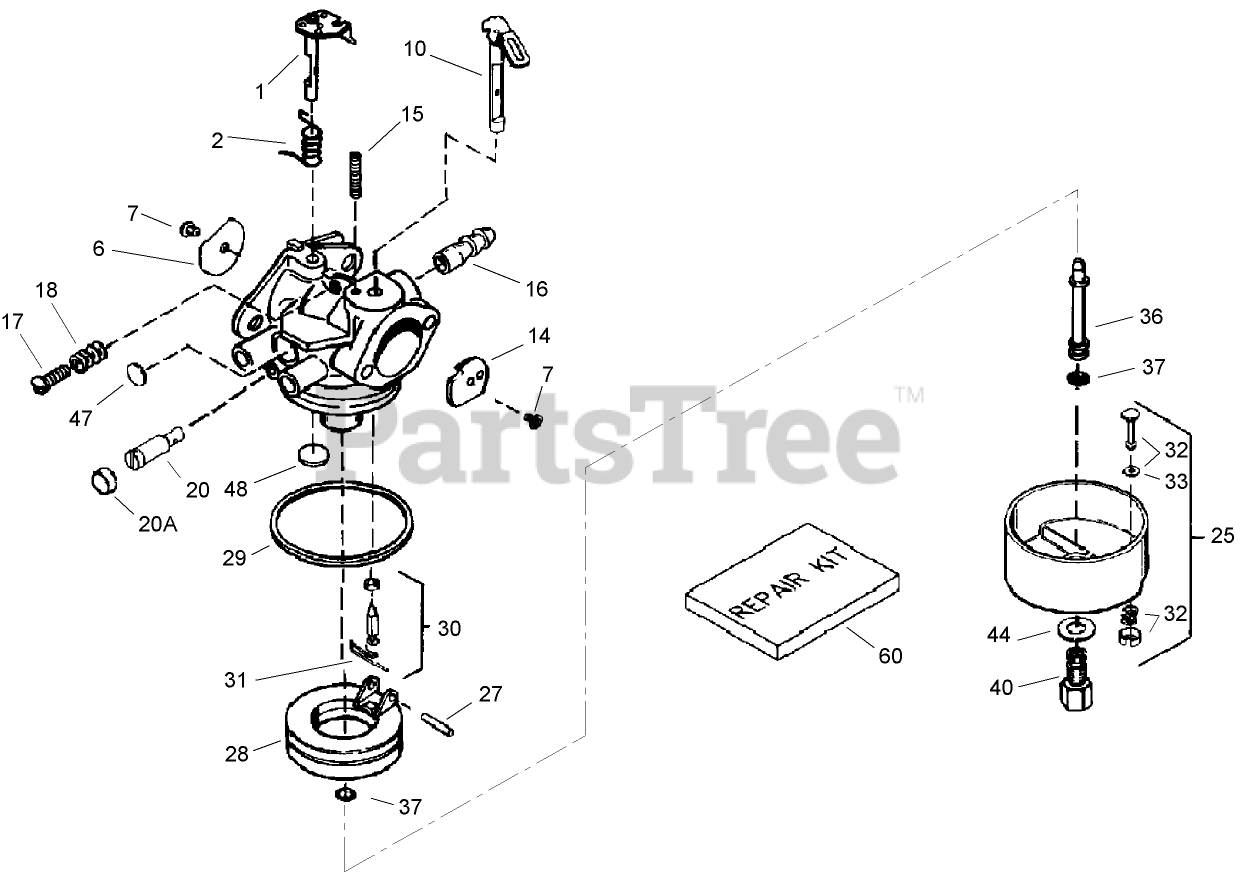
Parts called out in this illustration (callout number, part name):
1	Throttle Shaft and Lever ASM
2	Spring-Return, Throttle
6	Shutter-Throttle
7	Screw-Shutter
10	Choke Shaft and Lever ASM
14	Shutter-Choke
15	Spring-Positioning, Choke
16	Fitting-Fuel
17	Screw-Throttle Crack Screw / Idle Speed
18	Spring-Tension
20	Screw-Restrictor, Idle
20A	Cap-Screw, Idle Restrictor
25	Float Bowl Asm. (Incl. Ref. # 32, 33)
27	Shaft-Float
28	Float
29	O Ring-Bowl, Float
30	Inlet Needle, Seat Clip Assy. (Incl. No. 13)
31	Clip-Spring
32	Bowl Drain ASM
33	Gasket-Plunger, Drain
36	Tube-Nozzle, Main
37	O-Ring
40	Nut-High Speed, Bowl
44	Washer-Bowl Nut
47	Plug-Welch, Idle Mixture Well
48	Plug-Welch, Atmospheric Vent
60	Repair Kit
